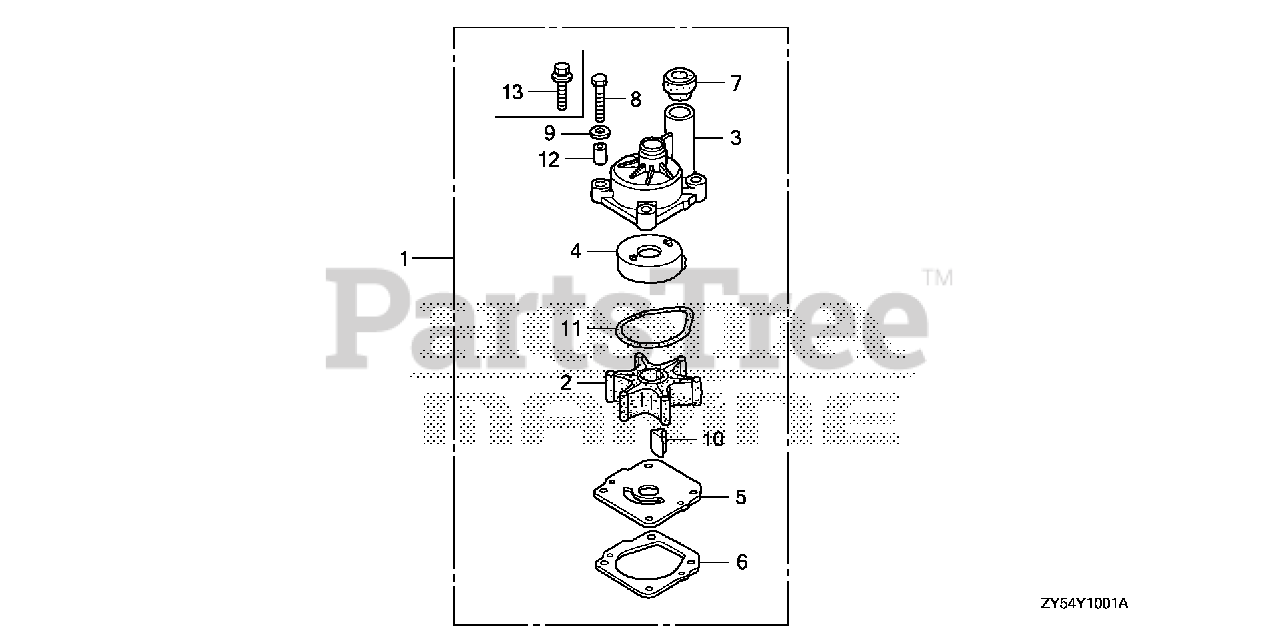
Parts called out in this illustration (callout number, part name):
1	PUMP KIT, IMPELLER
2	IMPELLER, PUMP
3	HOUSING, IMPELLER
4	LINER, PUMP
5	COVER, IMPELLER
6	GASKET B, IMPELLER
7	RING, WATER TUBE SEAL
8	BOLT, HEX. (8X40)
9	WASHER (8MM)
10	KEY, WOODRUFF
11	O-RING, WATER PUMP
12	COLLAR, DISTANCE
13	BOLT-WASHER (8X40)
